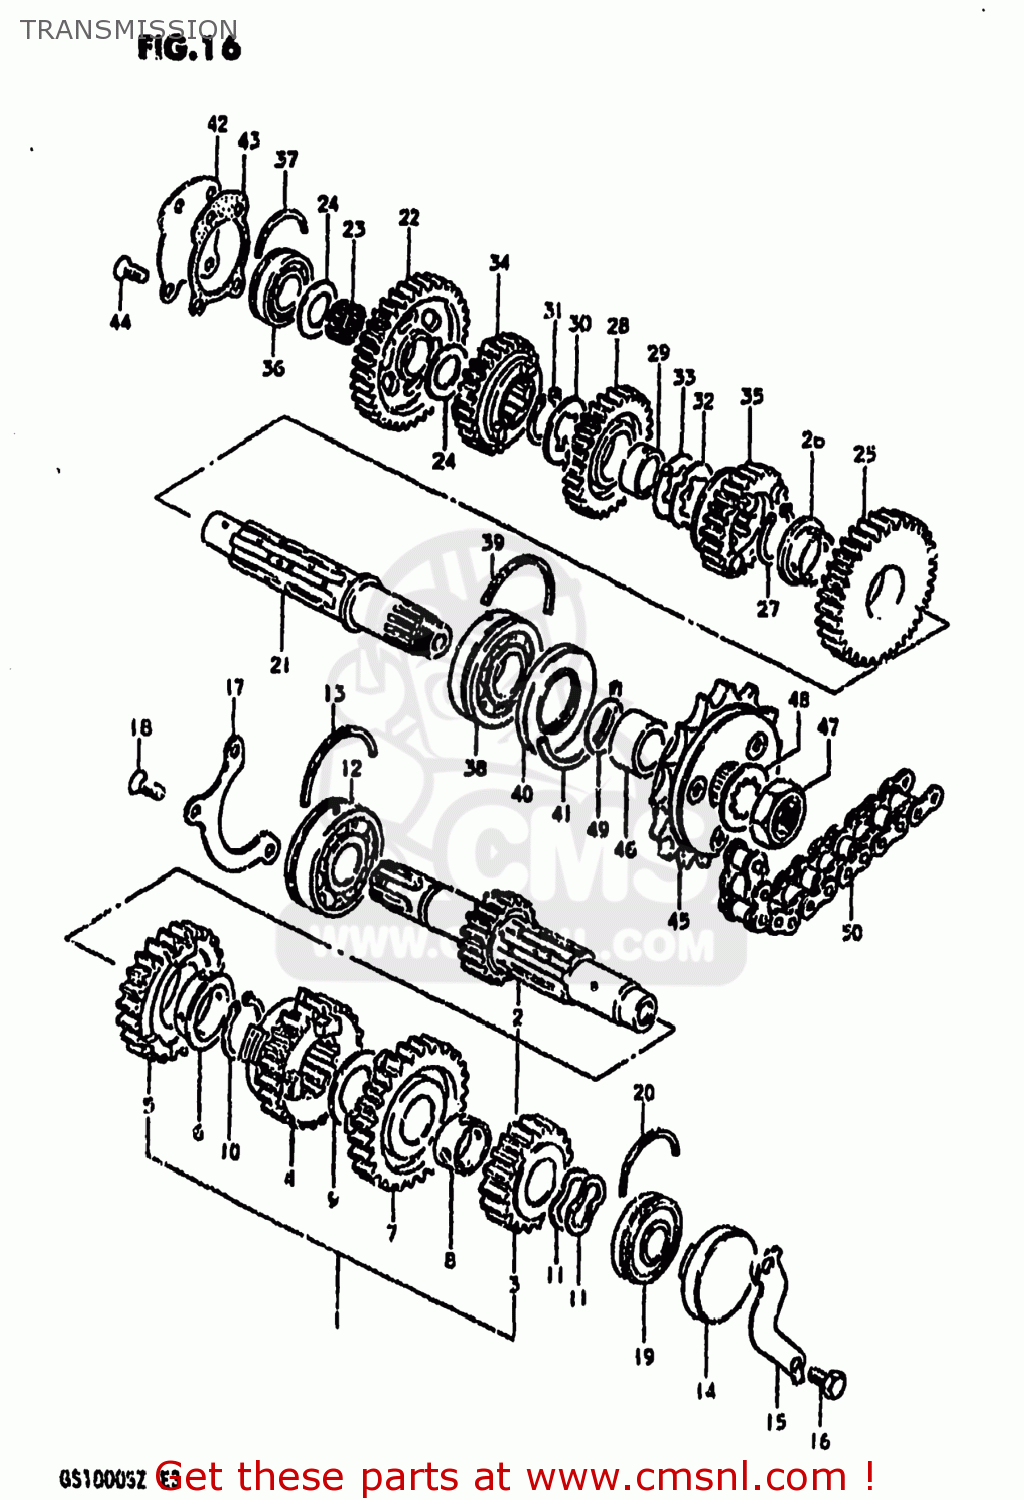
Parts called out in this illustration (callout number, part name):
1	SHAFT,COUNTER
2	SHAFT,COUNTER
3	GEAR,SECOND DRIVE
4	GEAR,3RD DRIVE(NT:21)
5	GEAR,FOURTH DRIVE
6	BUSH(28X32X2)
7	GEAR,FIFTH DRIVE
8	BUSHING
9	WASHER
10	CIRCLIP
11	WASHER
12	BEARING(25X62X17)
13	C-RING
14	PLUG
15	RETAINER,CL PUSH ROD OIL SEAL
16	BOLT
17	RETAINER,CNTR SHAFT BEARING
18	SCREW
19	BEARING(20X47X14)
20	C RING
21	SHAFT,DRIVE
22	GEAR,FIRST DRIVEN (NT:35)
23	BEARING(20X24X10).8
24	WASHER
25	GEAR,SECOND DRIVEN
26	BUSH(28X32X2)
27	CIRCLIP
28	GEAR,THIRD DRIVEN
29	BUSH,3RD DRIVEN GEAR
30	WASHER,LOCK
31	CIRCLIP
32	WASHER,LOCK
33	WASHER
34	GEAR,FOURTH DRIVEN
35	GEAR,FIFTH DRIVEN
36	BEARING
37	C RING
38	BEARING(25X62X17)
39	C-RING
40	SEAL,OIL(32X62X7)
41	C RING
42	PLATE,DRIVE SHAFT
43	GASKET,DRIVESHAFT PLATE (MCA)
44	SCREW
45	SPROCKET,ENGINE
46	SPACER(25X32X18.6)
47	NUT
48	WASHER
49	O RING(D:1,ID:24.5)
50	CHAIN ASSEMBLY,DRIVE
